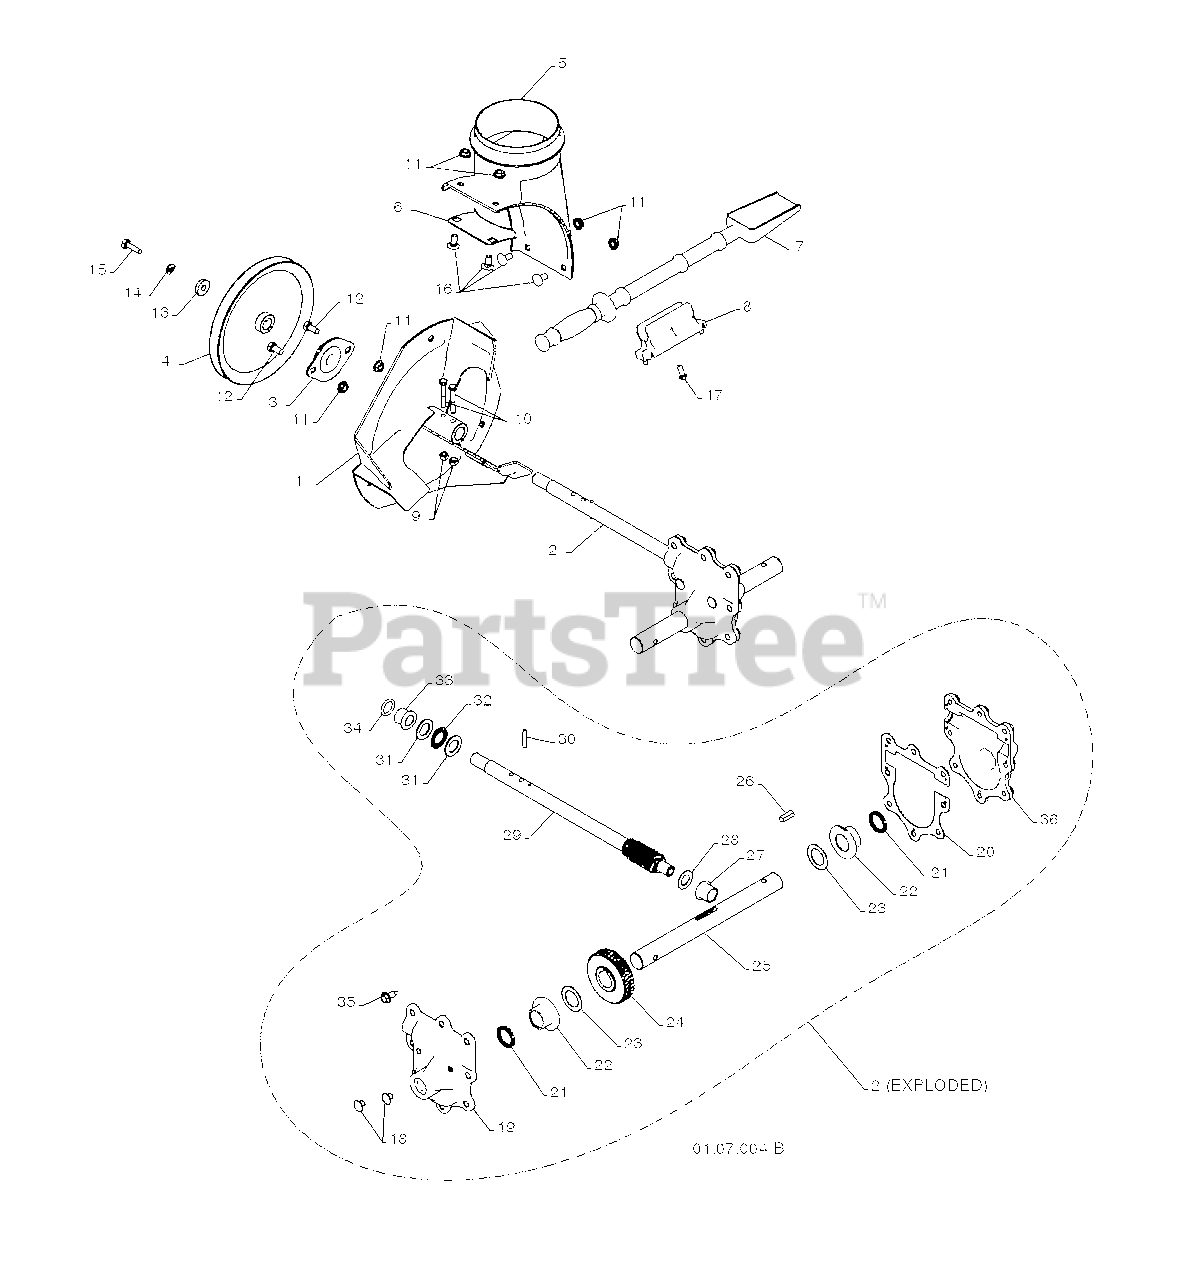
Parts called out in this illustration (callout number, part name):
1	IMPELLER
2	GEARBOX ASSEMBLY
4	IMPELLER PULLEY
5	DISCHARGE BASE
6	CORNER BRACKET
7	CLEAN OUT TOOL
9	NUT 1/4-20
10	SCREW 1/4-20 X .625
11	NUT 5/16-18
12	SCREW 5/16-18 X .625
14	LOCKWASHER 5/16
15	SCREW 5/16-18 X 1.00
16	CARRIAGE BOLT
17	SCREW 13-16 X .625
18	PLUG
19	GEARBOX COVER RH
20	GASKET
21	SEAL
22	BEARING
23	THRUST WASHER 1.00
24	WORM GEAR
25	AUGER SHAFT
26	SQUARE KEY
27	BEARING
28	THRUST WASHER
29	IMPELLER SHAFT
30	ROLL PIN
31	THRUST WASHER
32	THRUST BEARING
35	SCREW 5/16-18 X .750
36	GEARBOX COVER LH
